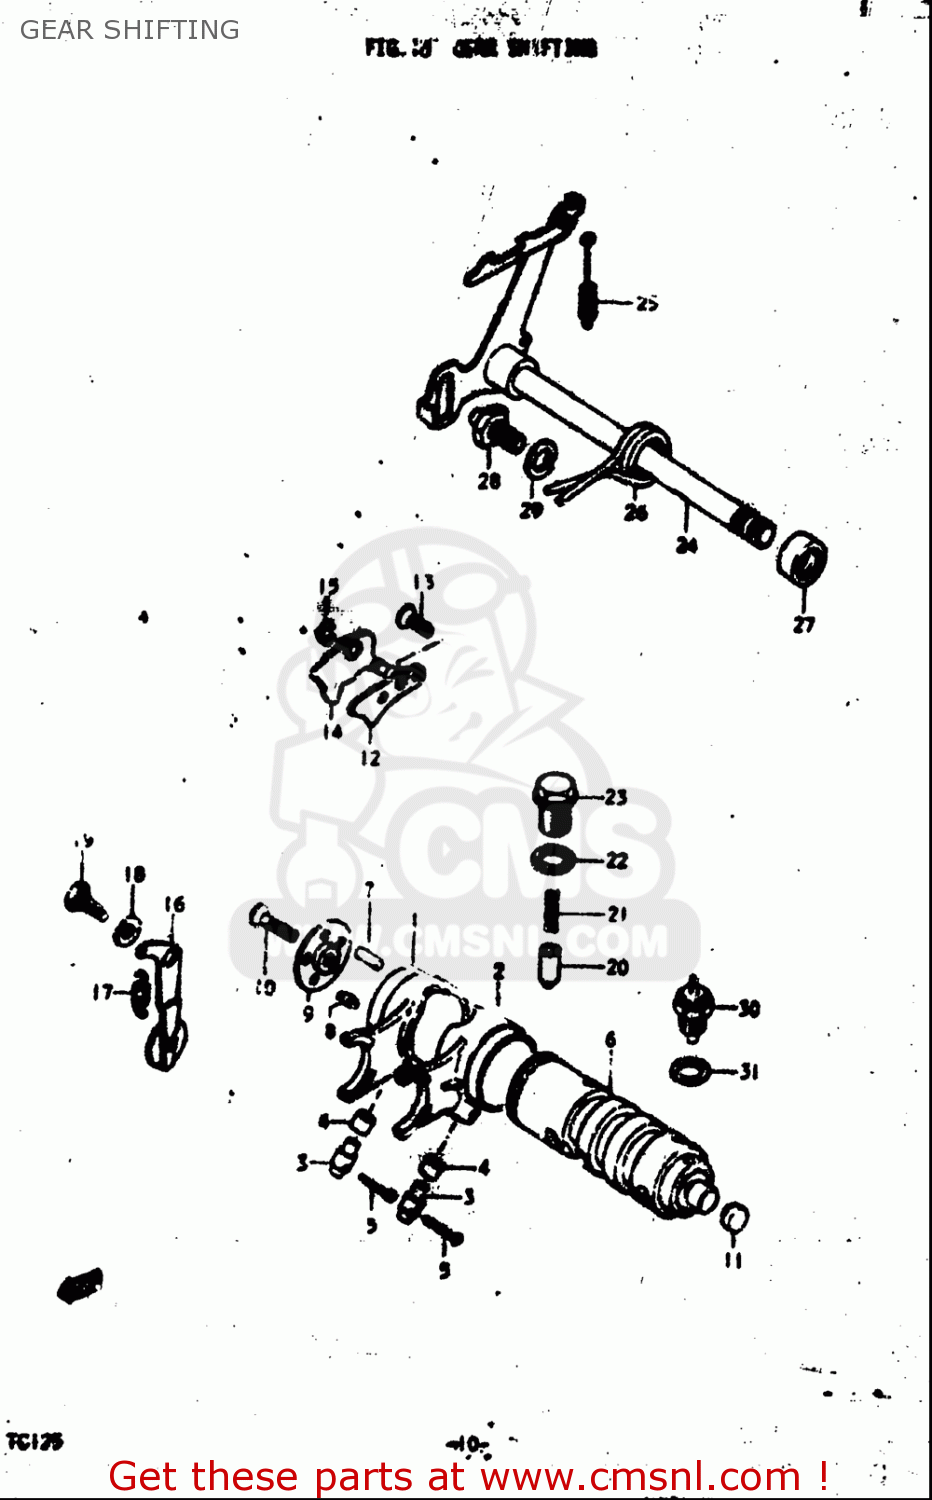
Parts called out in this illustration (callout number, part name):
4	SPACER(6X9.8X6)
5	PIN
7	ROLLER(4X13.8)
8	PIN
9	RETAINER,GEAR SHIFT CAM DR PIN
10	SCREW
11	PLUG
12	GUIDE,GEAR SHIFT CAM
13	SCREW
14	PAWL,GEAR SHIFT CAM STOPPER
15	E RING
17	SPRING
19	BOLT(6X16.1)
21	SPRING
22	GASKET, STOPPER HOUSING
23	HOUSING,GEAR SHIFT CAM STOPPER
24	SHAFT,GEAR SHIFT
25	SPRING
26	SPRING
27	SEAL,OIL (12X22X9)
29	WASHER,LOCK
31	GASKET(12.5X20X1) (NAS)
